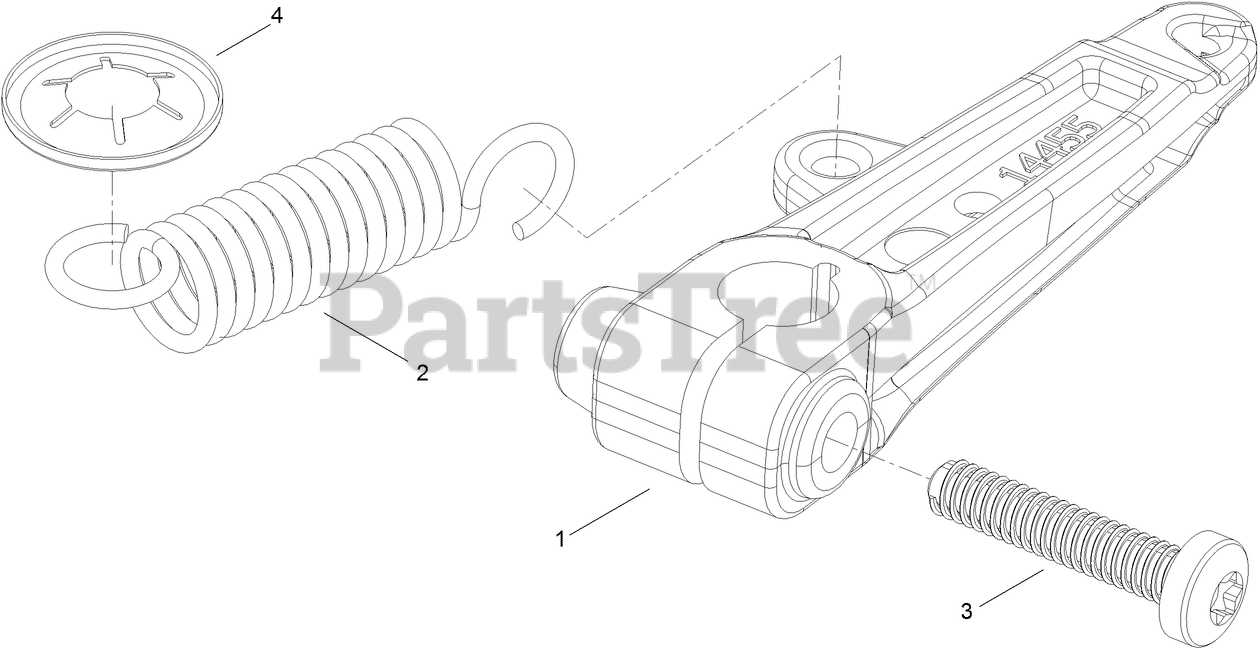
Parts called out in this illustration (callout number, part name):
1	LEVER-CLUTCH
2	SPRING-EXTENSION
4	WASHER-LOCK
